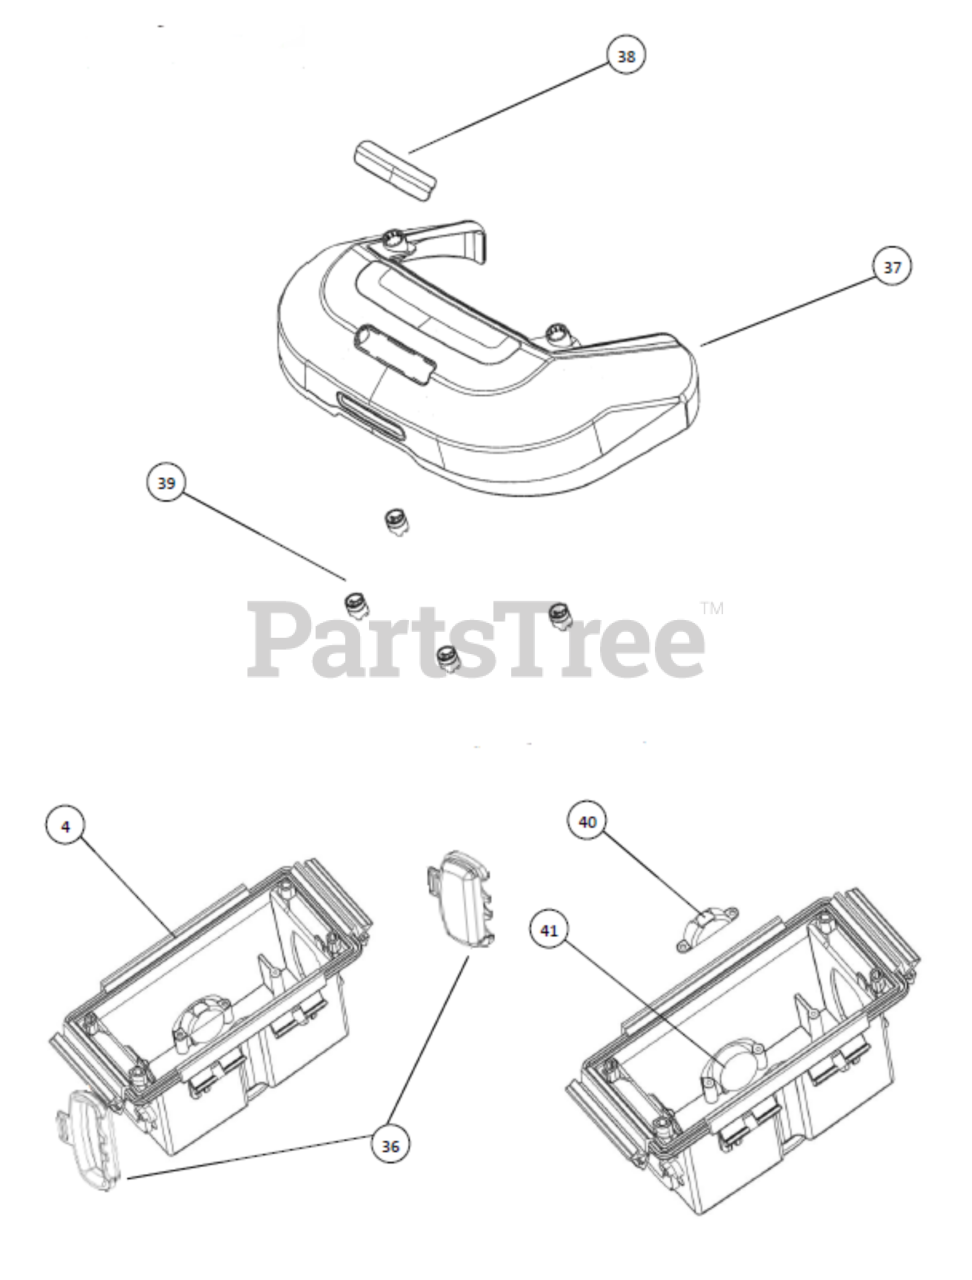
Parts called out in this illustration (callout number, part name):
4	C-BOX ASSEMBLY
36	C-BOX RUBBER DOOR
37	BUMPER ASSEMBLY BLACK
38	LIGHT COVER-BUMPER
39	BUMPER HANG CAVITY
40	BUZZER BRACKET
41	PIEZO BUZZER W/CAB
